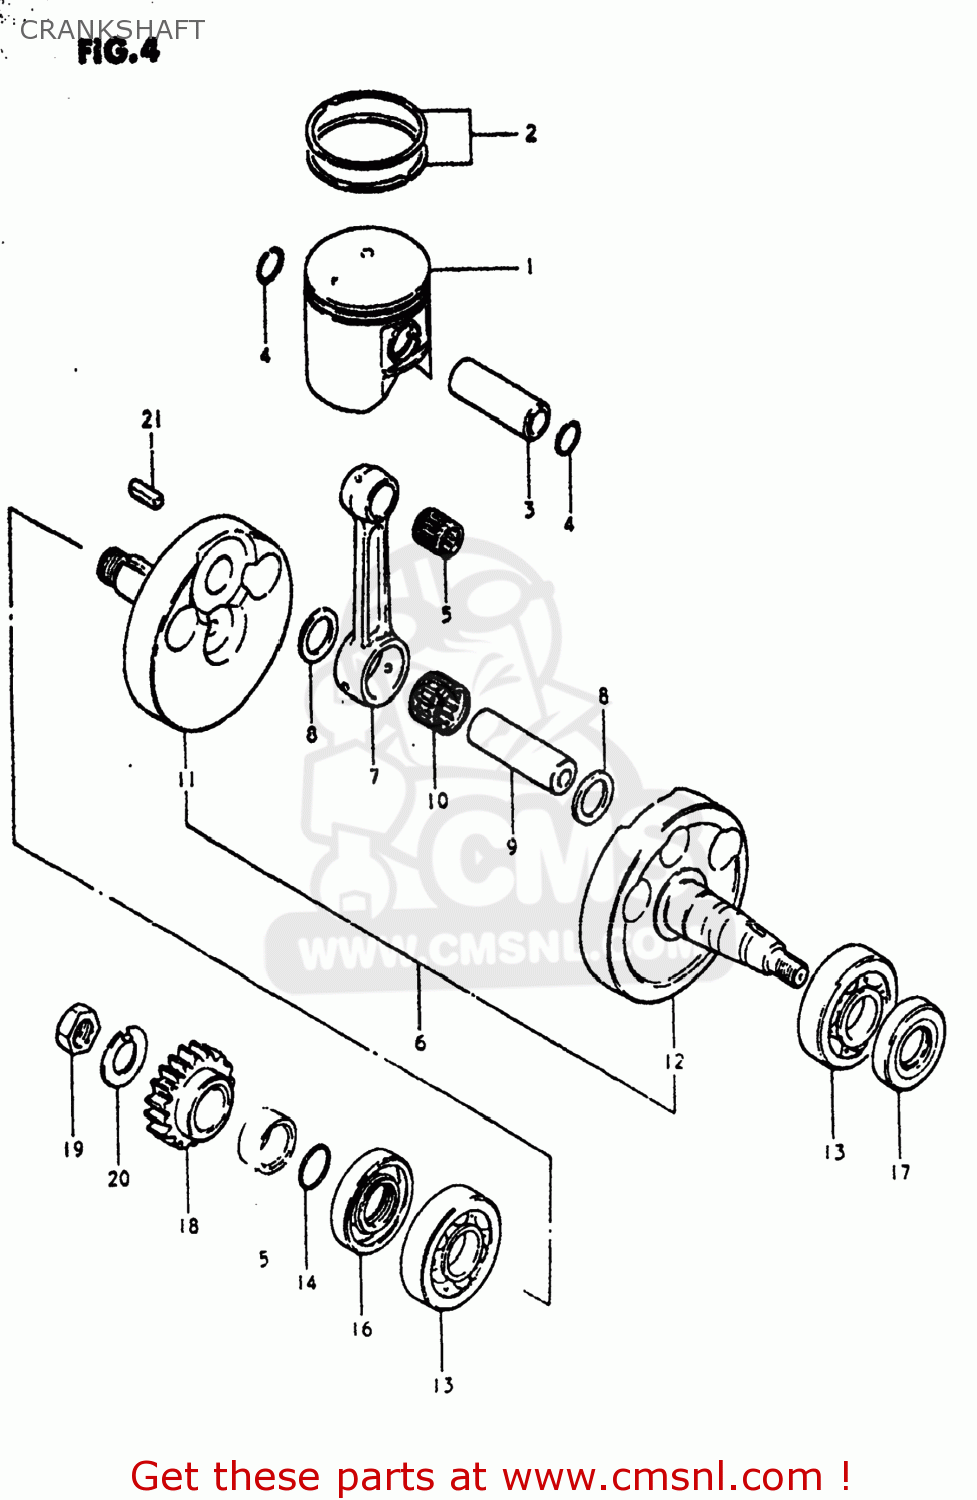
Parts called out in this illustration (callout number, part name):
1	PISTON (85.00MM)
2	RING SET,PISTON
3	PISTON PIN
4	CIRCLIP
5	BEARING(20X25X22)
6	CRANKSHAFT ASSEMBLY
7	ROD,CONNECTING
8	WASHER(24X29X2)
9	PIN,CRANK
10	BEARING
11	CRANKSHAFT
12	CRANKSHAFT,LEFT
13	BEARING
14	O RING(D:2.4,ID:21.8)
15	SPACER (22X37X12.5)
16	SEAL,OIL(37X62X9)
17	SEAL,OIL(24X50X9)
18	GEAR,PRIMARY DRIVE
19	NUT
20	WASHER
21	KEY
